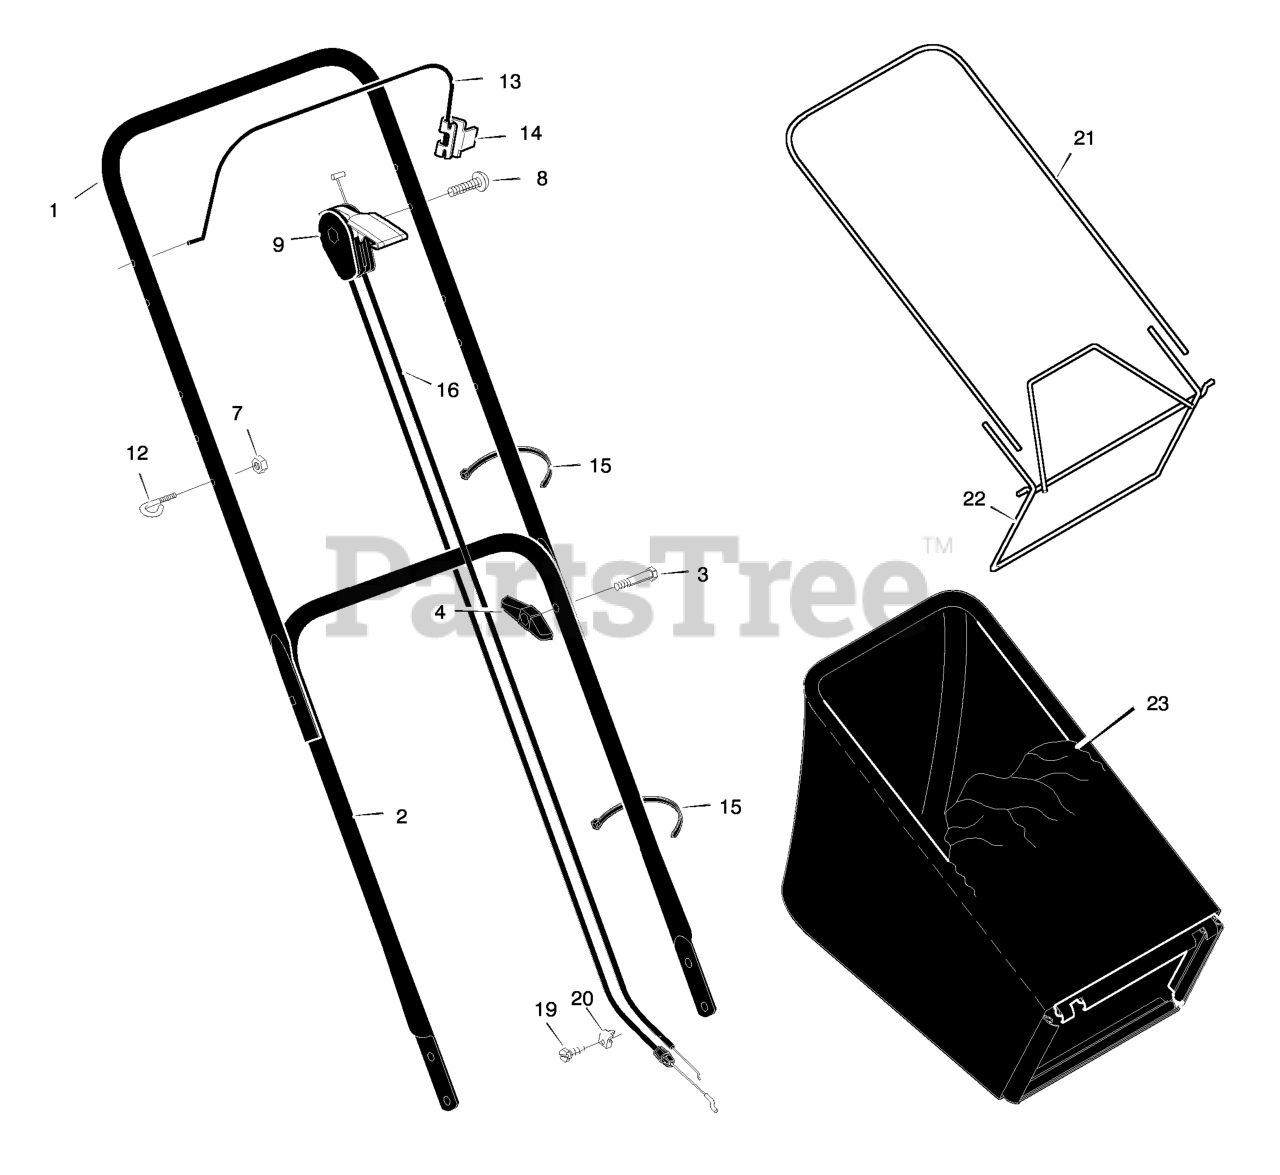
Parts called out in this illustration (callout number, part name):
1	Handle, Upper
2	Handle, Lower
4	Knob, Plastic
7	Locknut
9	Throttle Control
12	Guide, Rope
13	Engine Stop Lever
14	Bracket, Stop Lever
15	Fastener, Cable
16	Engine Stop Cable
21	Frame, Top
22	Frame Assembly
23	Bag, Cloth
